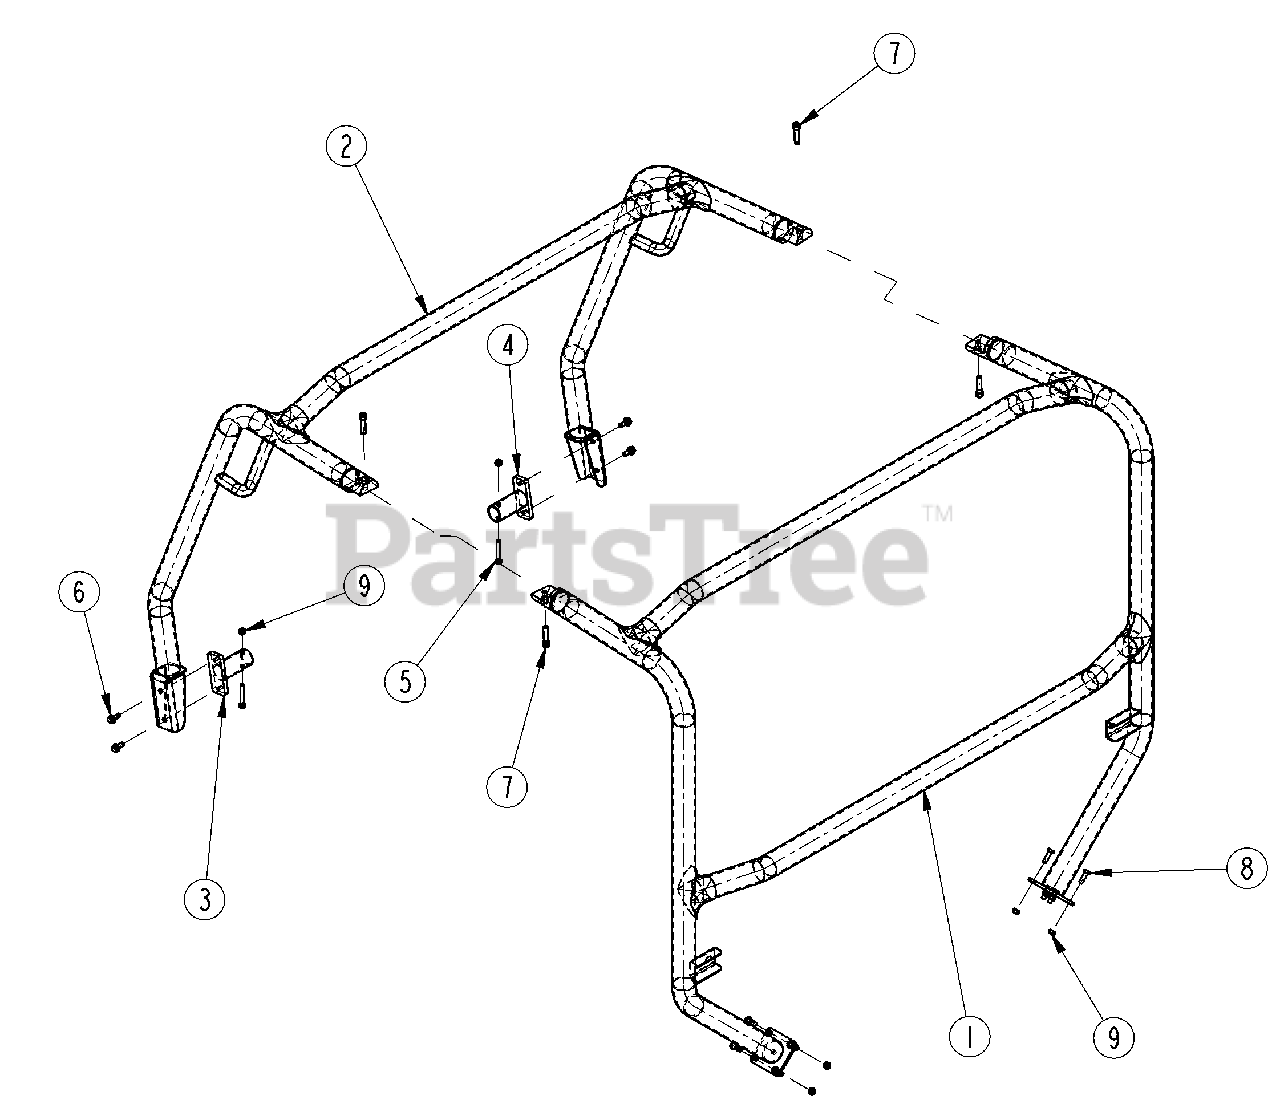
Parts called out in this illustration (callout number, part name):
1	WELDMENT, ACCESSORY BAR REAR
2	WELDMENT, ACCESSORY BAR FRONT
3	BAR MOUNT FRONT LH
4	BAR MOUNT FRONT RH
5	BOLT, HEX 5/16-18 X 2 GR5
6	HFS 5/16-18X3/4 GR5
7	HSHCS 3/8-16X1 1/2 Apply Loc-Tite®
8	BOLT, HEX 5/16-18X 1 GR5 Apply Loc-Tite®
9	NUT, NYLON LOCK 5/16-18 PLT
